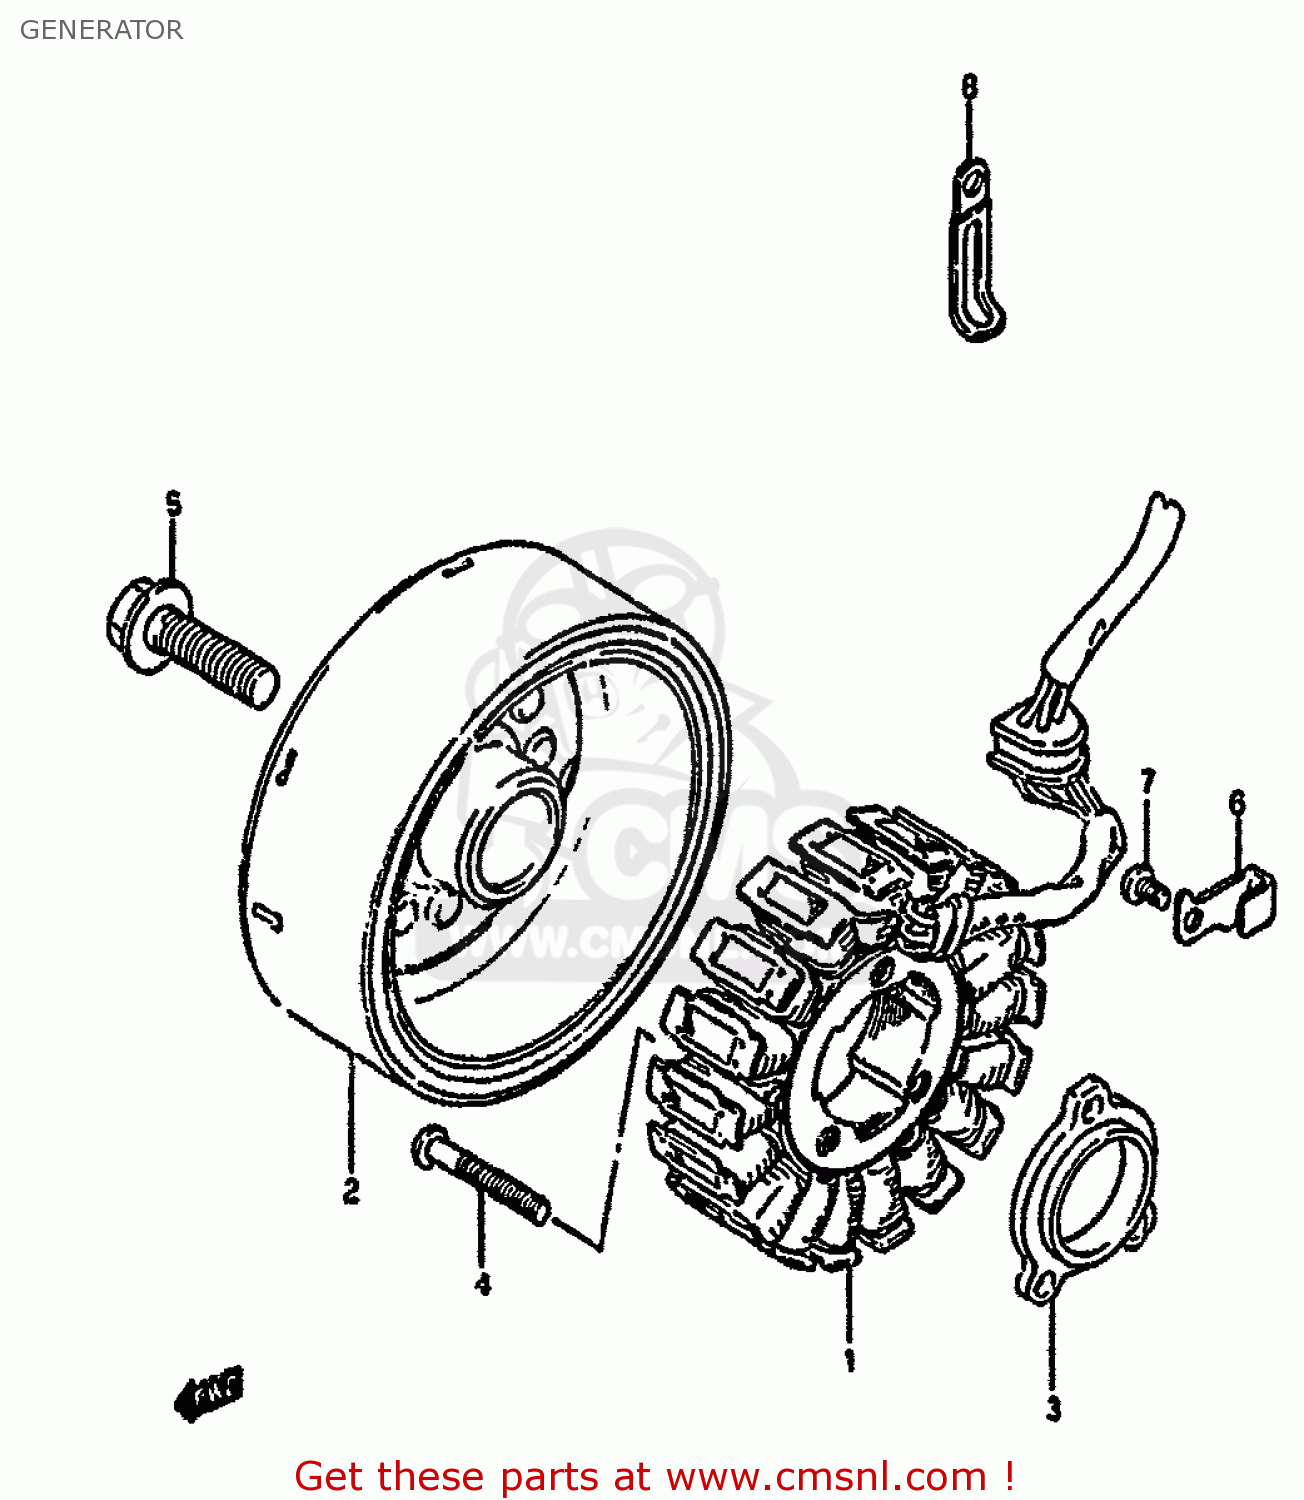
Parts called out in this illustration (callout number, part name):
1	STARTER ASSY
2	ROTOR
3	SPACER,GENERATOR STATOR
4	SCREW
5	BOLT(12X40)
6	CLAMP,GENERATOR LEAD WIRE
7	SCREW
8	CLAMP
